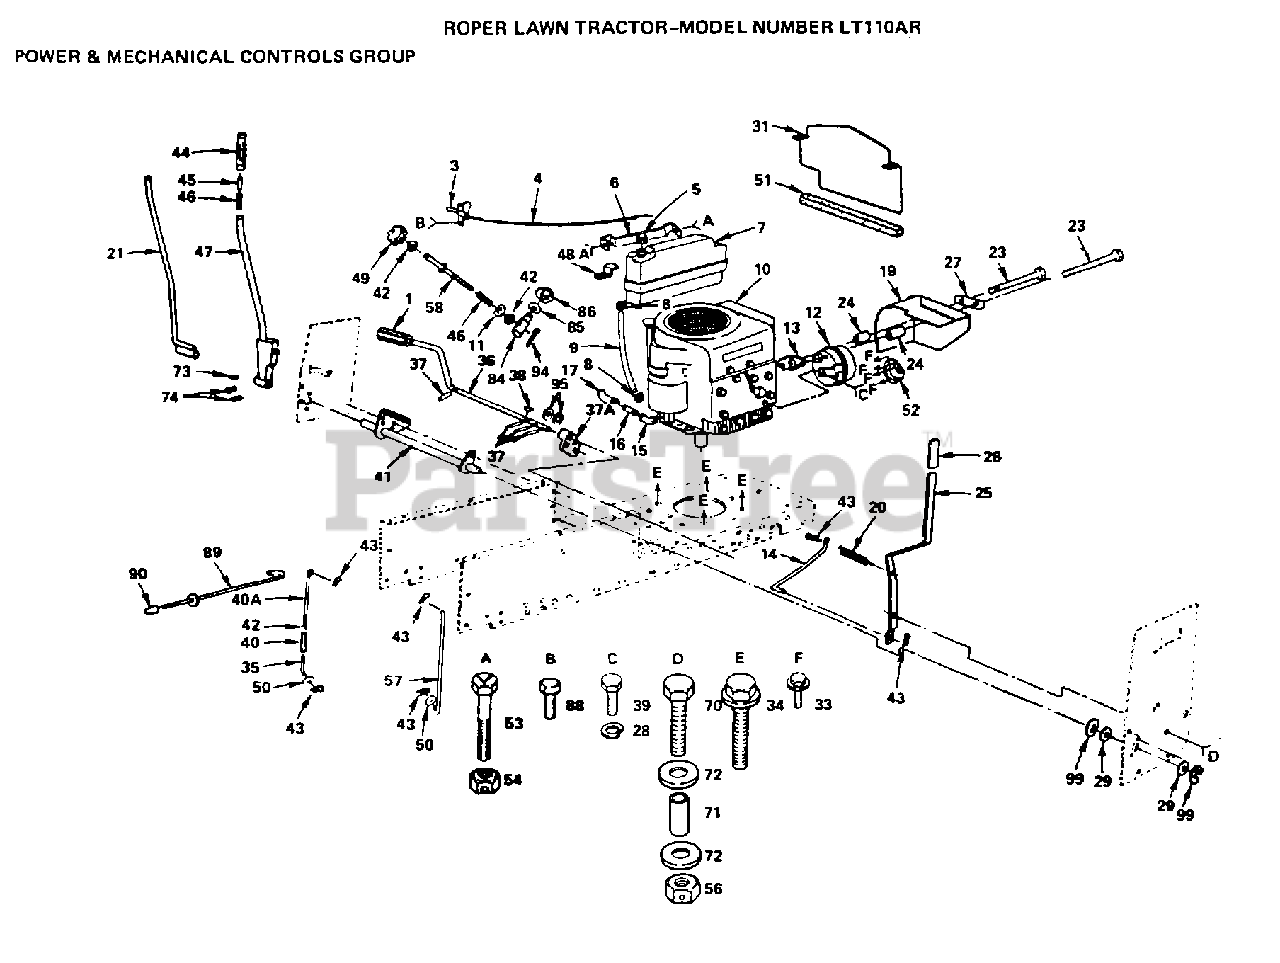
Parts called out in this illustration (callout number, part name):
1	PEDAL COVER T
6	SUPPORT-TANK LT
9	HOSE T
11	WASHER
12	MUFFLER LTV
19	BAFFLE ASSY LT
20	"SPRING.EXT.8.5"""
21	ROD ASSY-LEVER LT
24	SPACER LT
25	HANDLE-CLUTCH L
27	CLIP-MUFFLER LT
28	LOCKWASHER
29	WASHER
31	"VERTICAL LT, BAFL"
34	SCREW
39	BOLT
41	SHAFT ASSY YTV
42	NUT
44	HANDLE GRIP T
46	SPRING T
47	LEVER ASSY LT
48	BRACE-TANK LT
50	WASHER
52	DEFLECTOR.222573
53	BOLT
58	ROD ADJUST LT
71	BUSHING LT
85	WASHER
86	KLIP RING
88	SCREW
90	PLUNGER CAP T
99	RING
